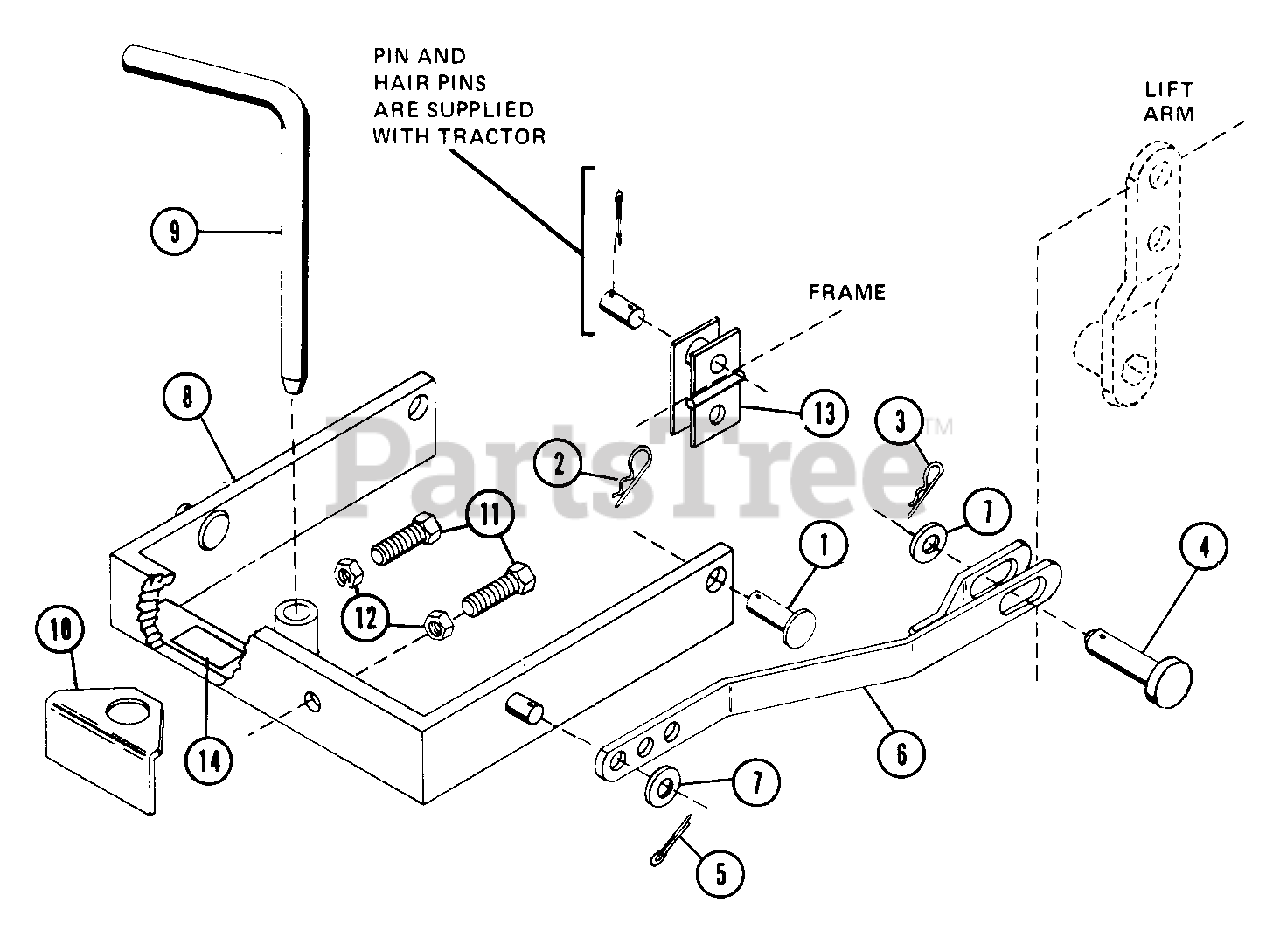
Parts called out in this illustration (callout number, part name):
1	CLEVIS PIN
2	PIN-HAIR INT .09X.62X2.25
3	PIN-HAIR INT .09X.188 PL
4	CLEVIS PIN
5	PIN-COTR .12X1.0 PL
6	LIFT STRAP
7	WSHR-FL-STL .531X1.062X.095 PL
8	BAIL ASSEMBLY
9	HITCH PIN
10	STABILIZER PLATE
11	BLT-HEX .62-11X2.25 GR2
12	NUT-HEX .625-11
13	ADAPTER HITCH PIVOT
14	DECAL - CAUTION
